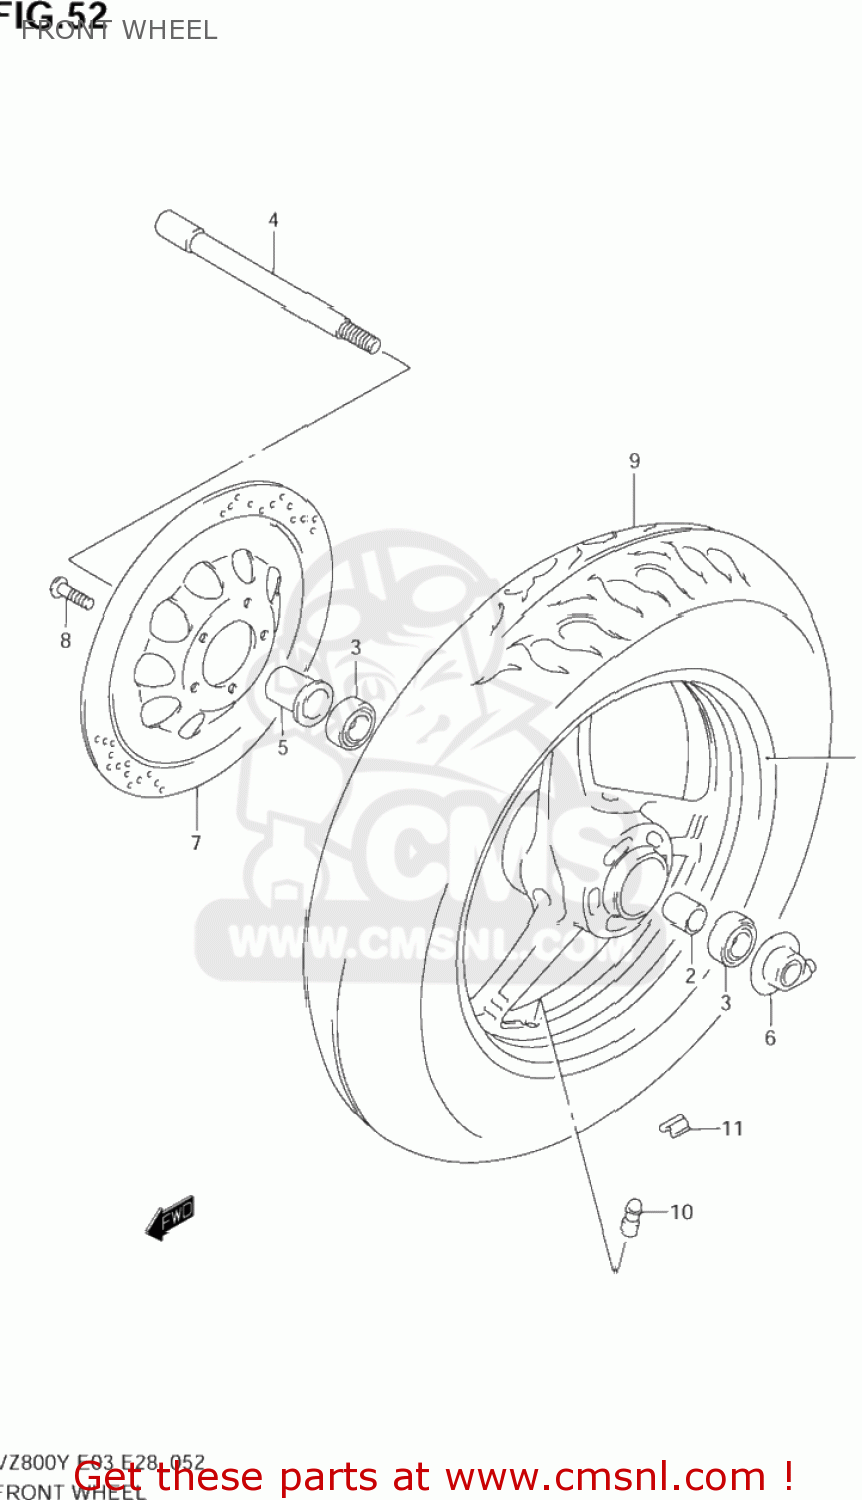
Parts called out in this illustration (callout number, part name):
1	WHEEL,FRONT (16XMT3.00)
2	SPACER(17.5X25X82.1)
3	BEARING
4	AXLE,FR
5	SPACER COMP,FRONT AXLE
6	BOX ASSY,SPEEDOMETER GEAR
7	DISC,FR BRAKE,R
8	BOLT 8X33
9	TIRE,FR(130/90-16 67H)
10	VALVE ASSY,WHEEL RIM(TR412)
11	BALANCER,WHEEL (10G)
